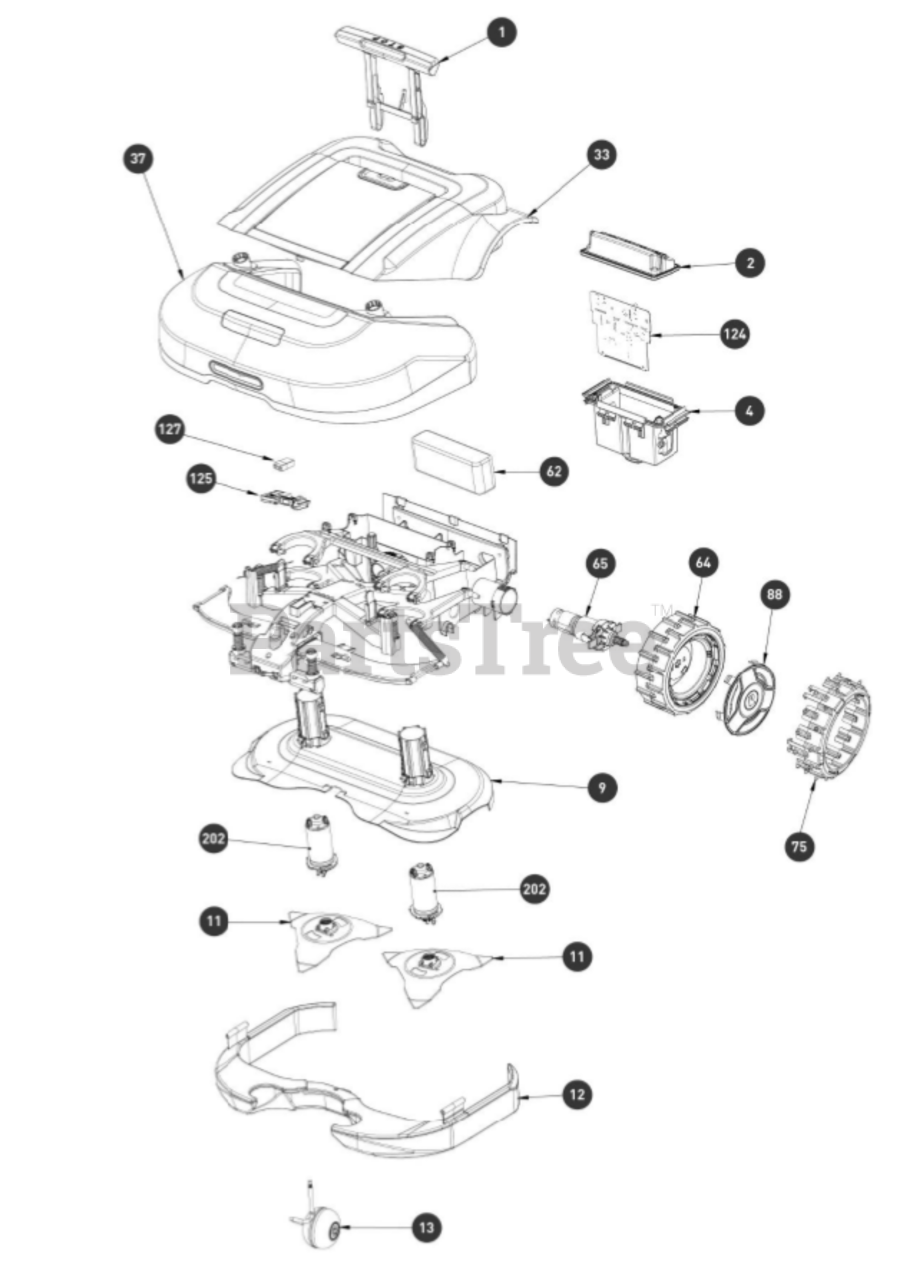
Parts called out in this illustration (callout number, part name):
1	CARRYING AND STOP HANDLE
2	LCD PANEL ASSEMBLY
4	C-BOX ASSEMBLY
9	MOWING DECK ASSEMB
11	HIGH CUT BLADE SET KIT
11	2 BLADE KIT-RS MOD
12	FLOATER ASSEMBLY
13	FRONT WHEEL ASSEMBLY (2014)
33	COVER ASSEMBLY (GREEN)
33	RS DOOR SHUTTER KIT
37	BUMPER ASSEMBLY BLACK
62	BATTERY-RS612/RS62
64	POWER WHEEL S
64	POWER WHEELS (W/CAP)
64	WHEEL LOCK
65	HD DRIVE MOTOR ASMALUMINUM SPLINE
75	ROBOGRIPS (RS)
88	RS PREMIUM TAS
124	RS MAIN BOARD (2019)
125	GSM W/GPS US (CATM1)
127	9V BATTERY
127	9V BATTERY CASE
127	9V BATTERY COVER
127	9V BATTERY CABLE
202	MOWING MOTOR BRUSH
